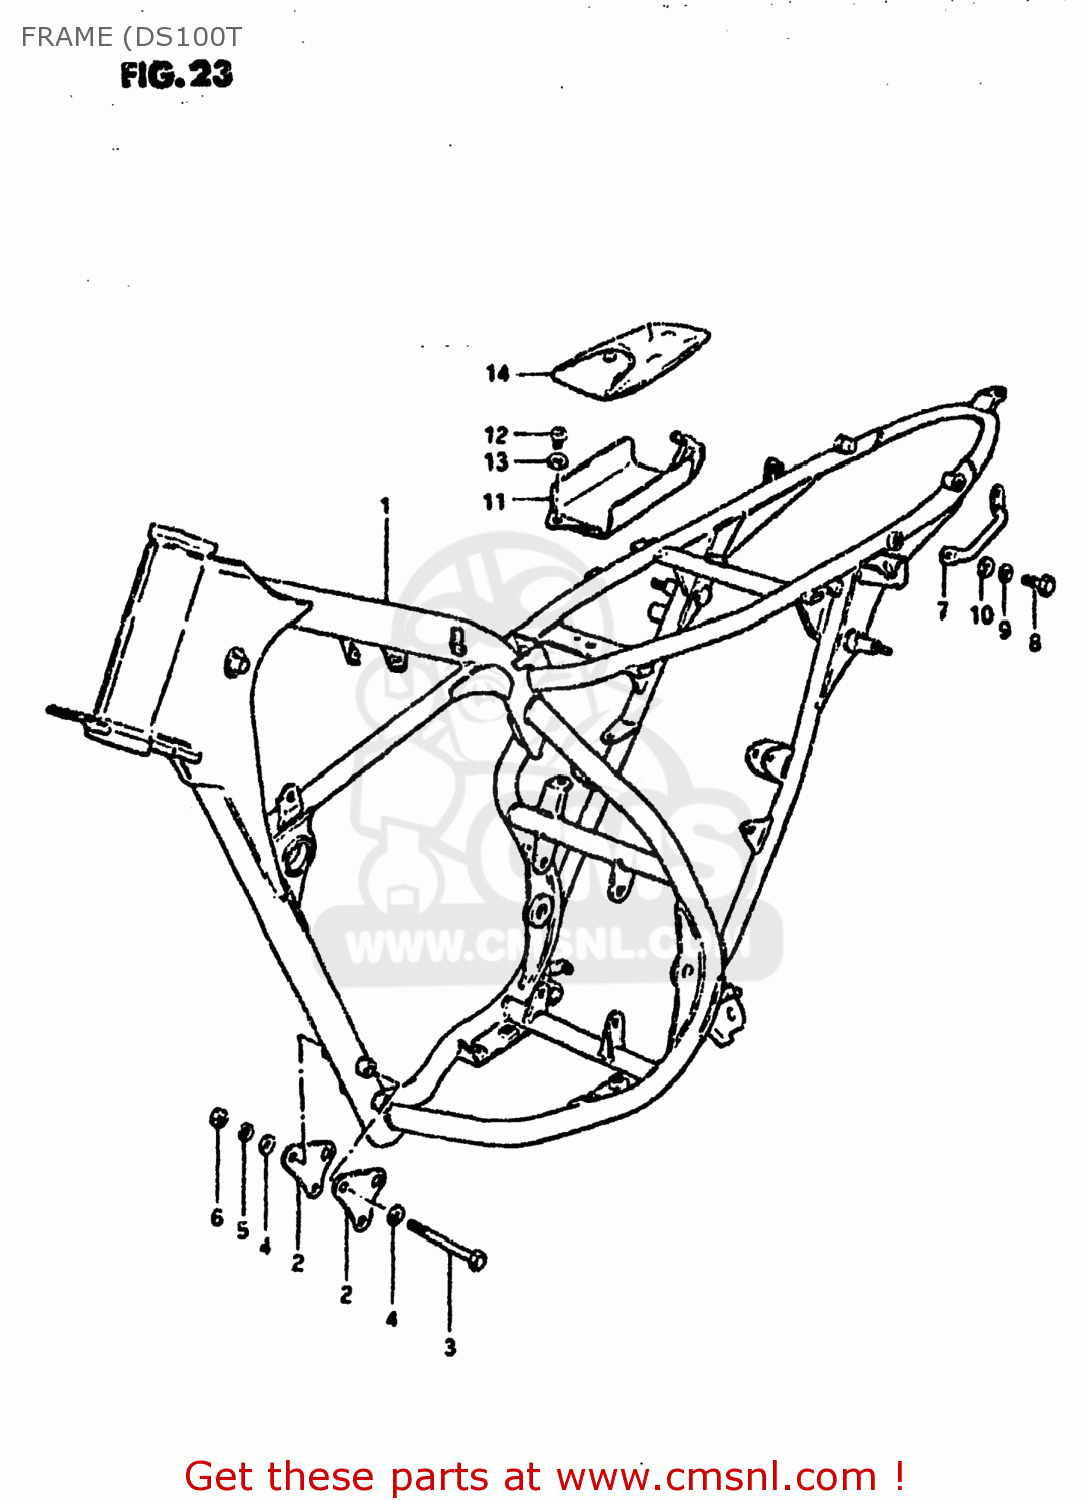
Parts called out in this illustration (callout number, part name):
1	FRAME
2	PLATE,ENG MTG
3	BOLT,8X75
4	WASHER
5	LOCK WASHER
6	NUT
7	GRIP,FRAME HANDLE
8	BOLT
9	LOCK WASHER
10	WASHER
11	HOLDER,TOOL
12	SCREW
13	WASHER
14	TOOL SET
